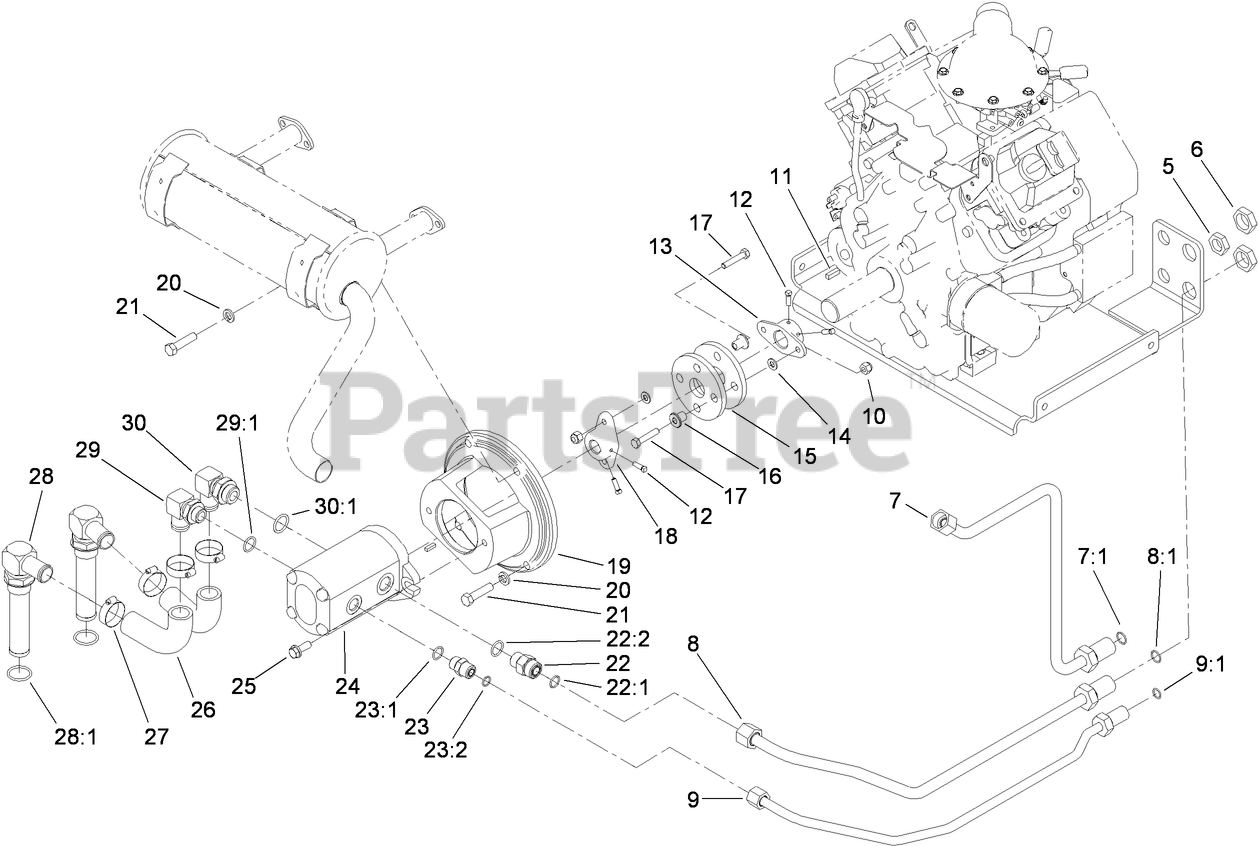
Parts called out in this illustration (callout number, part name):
5	NUT-BULKHEAD
6	NUT-LOCK, BULKHEAD
7	HYD TUBE ASM
7:1	O-RING
8	HYD TUBE ASM
8:1	O-RING
9	HYD TUBE ASM
9:1	O-RING
10	NUT-LOCK, NI
11	KEY-SQUARE
12	SCREW-SQH
13	HUB-ENGINE
14	WASHER-PLAIN
15	COUPLING-RUBBER
16	SPACER
17	SCREW-HH
18	HUB-PUMP
19	MOUNT-PUMP
20	WASHER-LOCK
21	SCREW-HH
22	FITTING-STRAIGHT
22:1	O-RING
22:2	O-RING
23	FITTING-STRAIGHT
23:1	O-RING
23:2	O-RING
24	HYD PUMP ASM
25	SCREW-HHF
26	HOSE-SUCTION, FORMED
27	CLAMP-HOSE
28	STRAINER FITTING ASM
28:1	O-RING
29	STEM-HOSE, 90 DEG
29:1	O-RING
30	FITTING-HYD, 90 DEG
30:1	O-RING
